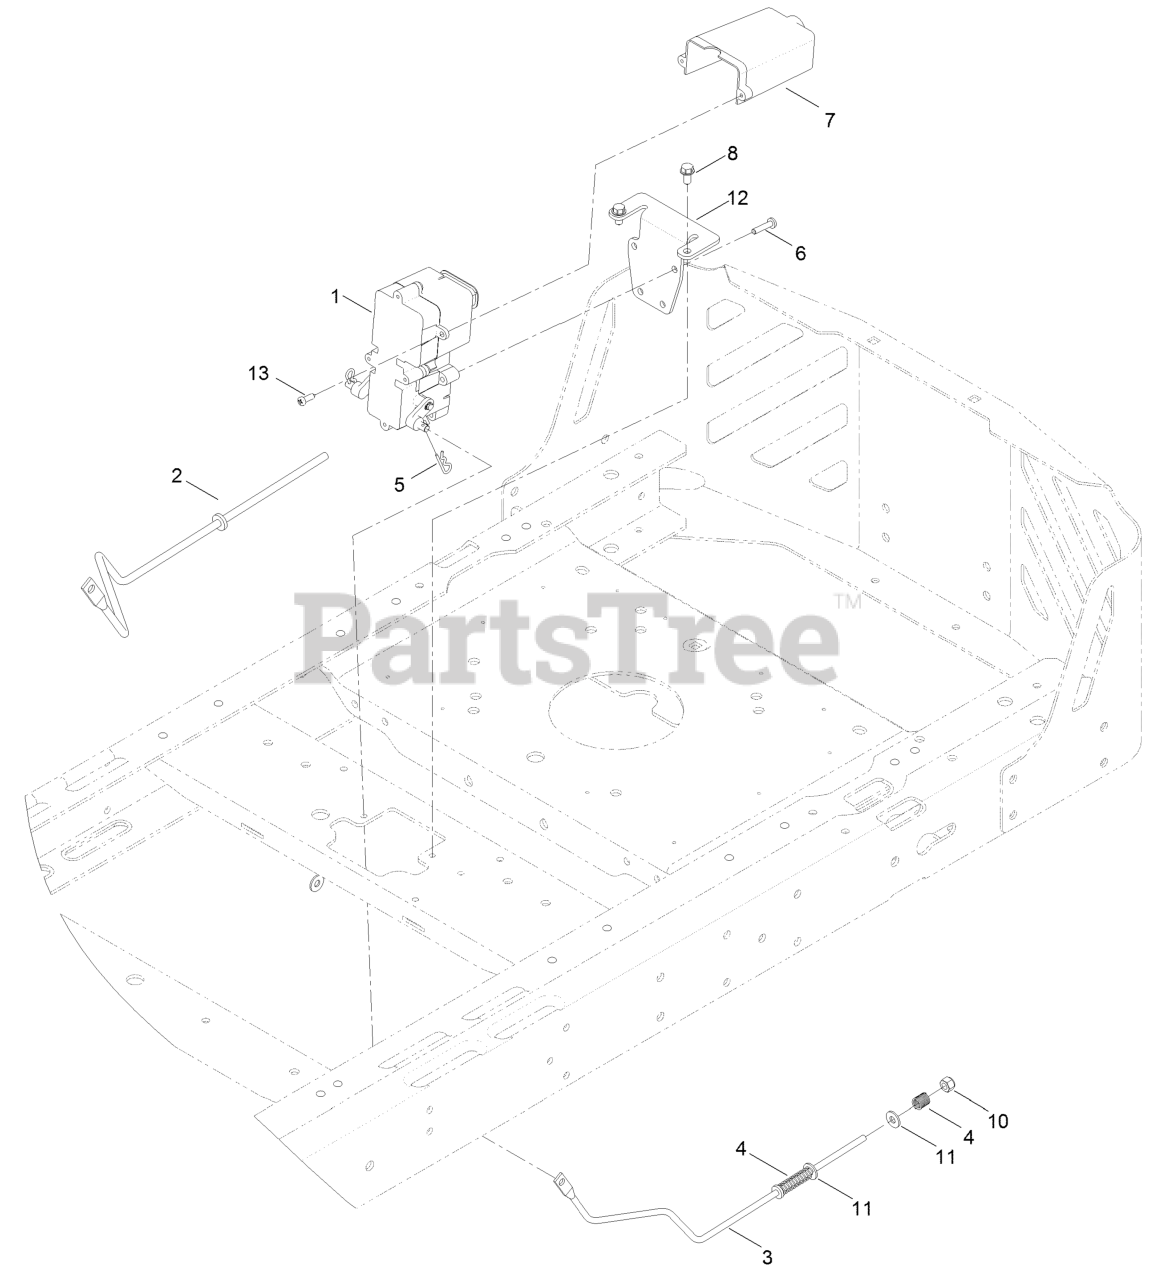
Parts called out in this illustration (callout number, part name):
2	ROD-BRAKE, RH
3	ROD-BRAKE, LH
4	SPRING-COMPRESSION
6	SCREW-PPH
8	SCREW-HWH
10	NUT-LOCK, NI
12	BRACKET-MOUNT, BRAKE
13	SCREW-PPH
